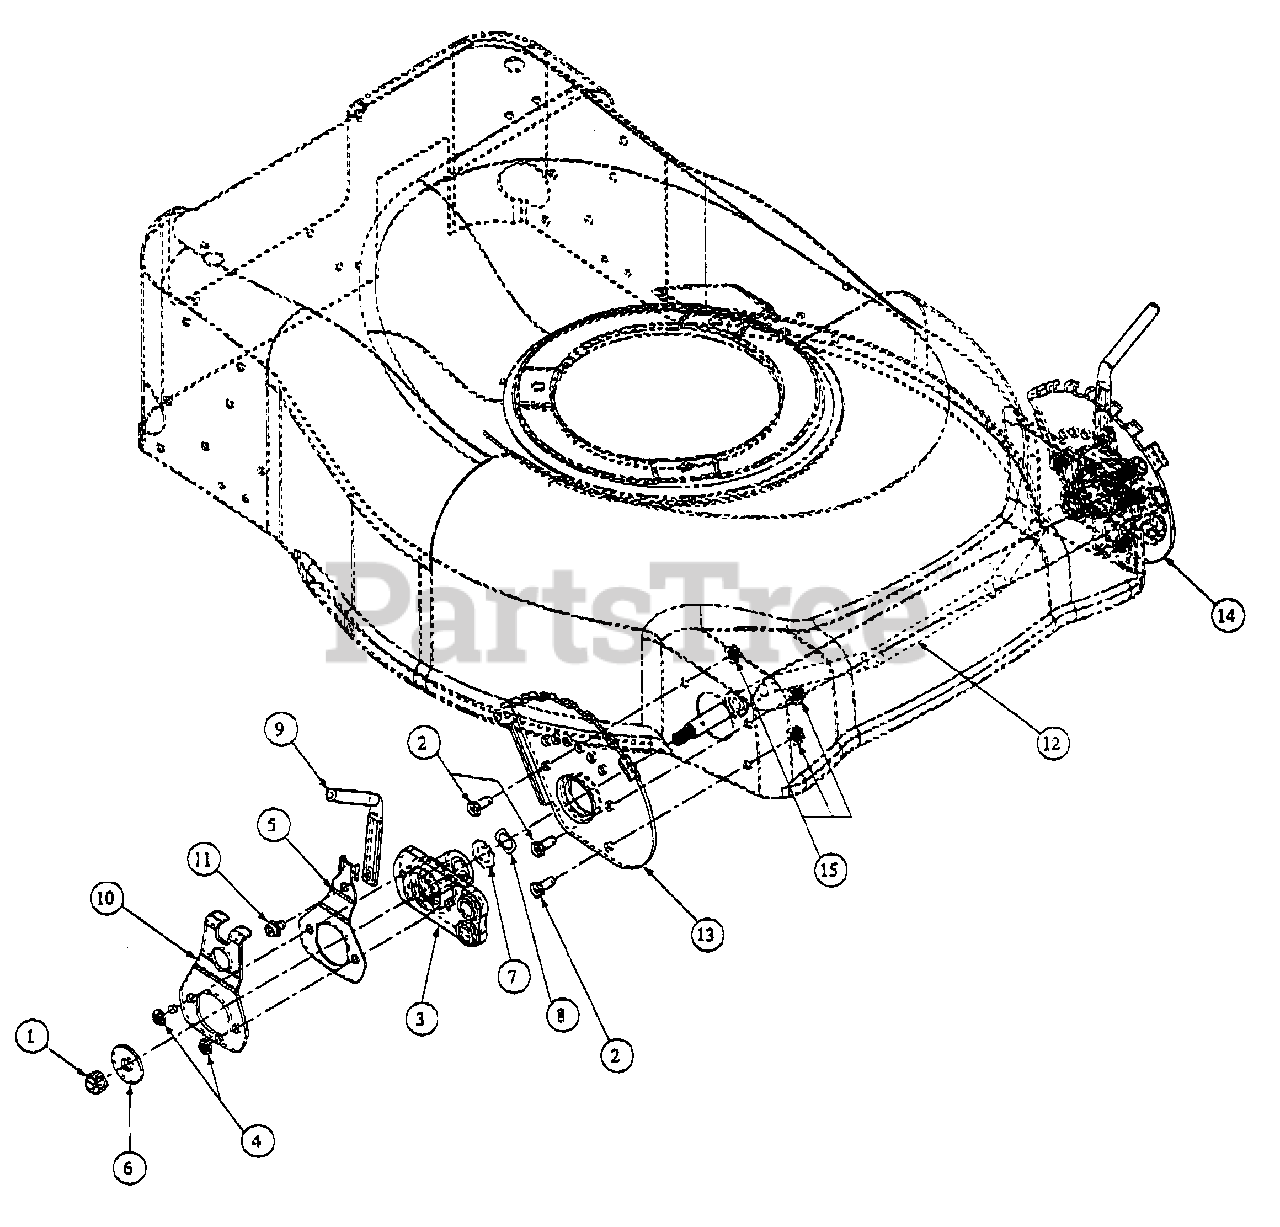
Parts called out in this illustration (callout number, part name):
1	L-Nut, 3/8-16, NYL INS. GR A. Z
2	HHCS, 1/4-20, .620, GR5, Standard
3	Pivot Wheel Bracket Assembly, 2 POS
4	Screw, TT, 1/4-20, 0.625, PANTRXI
5	Plate, Spring Height Adjuster
6	Flat Washer, .411 x 1 .25 x .100
7	Flat Washer, .536 ID x .781 OD x .01
8	Wave Washer, .531 ID x .781 OD x .01
9	Height Adjustment Handle
10	Spring Lever Support Bracket
11	Screw, TT, 1/4-20, 0.375, Hex Indicator Washer
12	Front Axle, .500 OD
13	Height Adjustment Bracket, Right Front
14	Height Adjustment Bracket, Left Front
15	Nut, 1/4-20, Hex Flange, Lock, Group F
